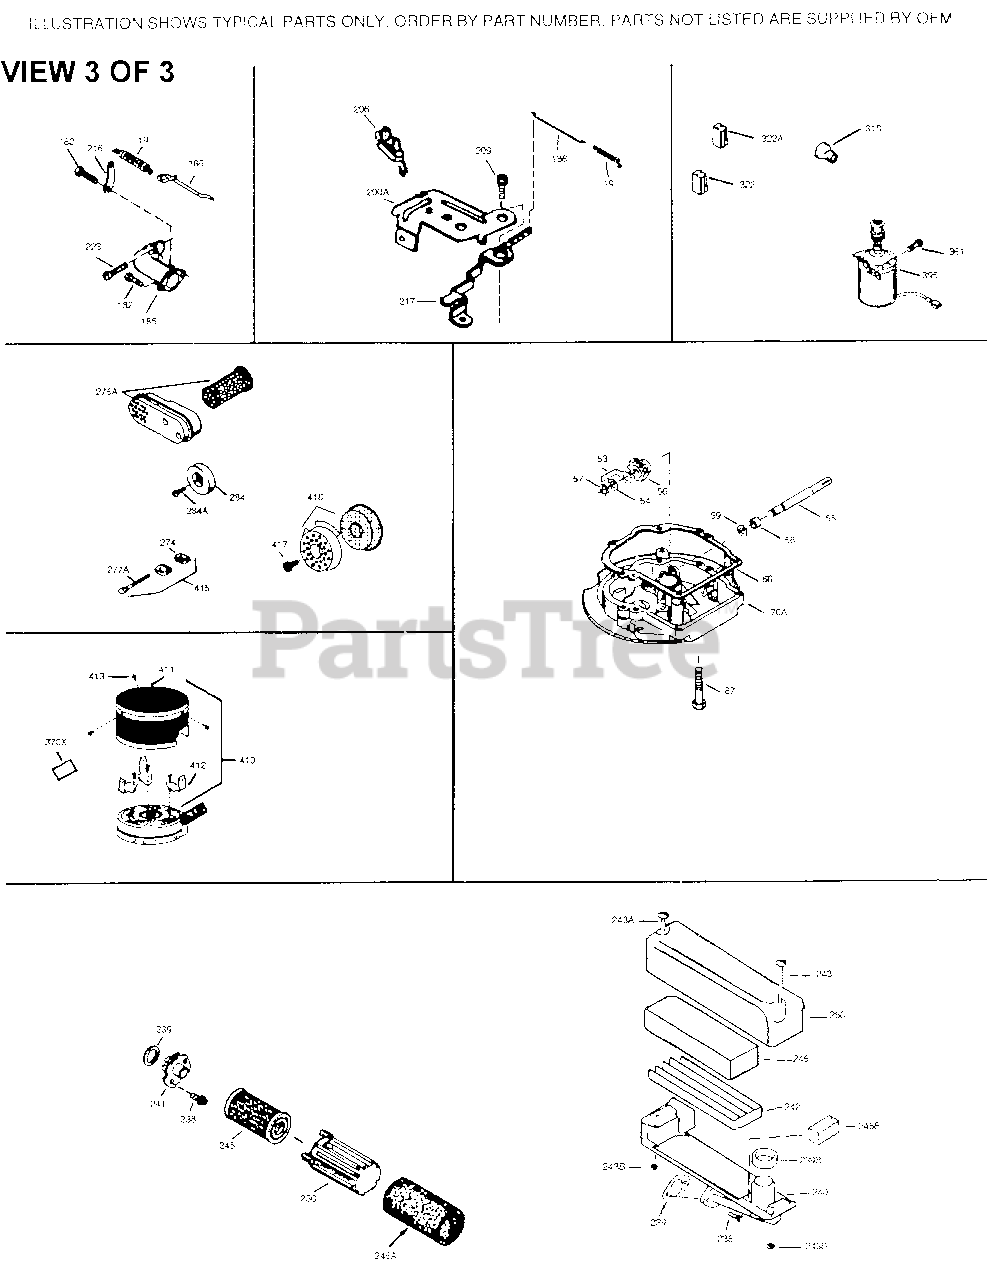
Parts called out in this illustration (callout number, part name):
19	Extension Spring
69	* Mounting Flange Gasket
182	Screw, 1/4-28 x 7/8"
185	Intake Pipe (Incl. 224)
186	Governor Link
209	Screw, 10-24 x 9/16"
223	Screw, 1/4-20 x 1"
238	Screw, 10-32 x 49/64"
239	* Air Cleaner Gasket
241	Air Filter Collar
245	Air Filter (Paper) (also available in Packaged Part #740095 (Qty.2))
250	Air Filter Cover (Craftsman)
275A	Spark Arrestor Muffler (Optional) (In cl. 284,284A,416,417)
284	Muffler Deflector (Incl. 284A) Option al
284A	Screw, 8-32 x 3/8" (Optional)
370B	Control Decal
416	Spark Arrestor Kit (Incl. 417) Option al
417	Screw, 8-32 x 3/8" (Optional)
999	Summer Maintenance Kit (incl. Oil, Sp ark Plug, Air Cleaners (2), & Ultra-F resh)
